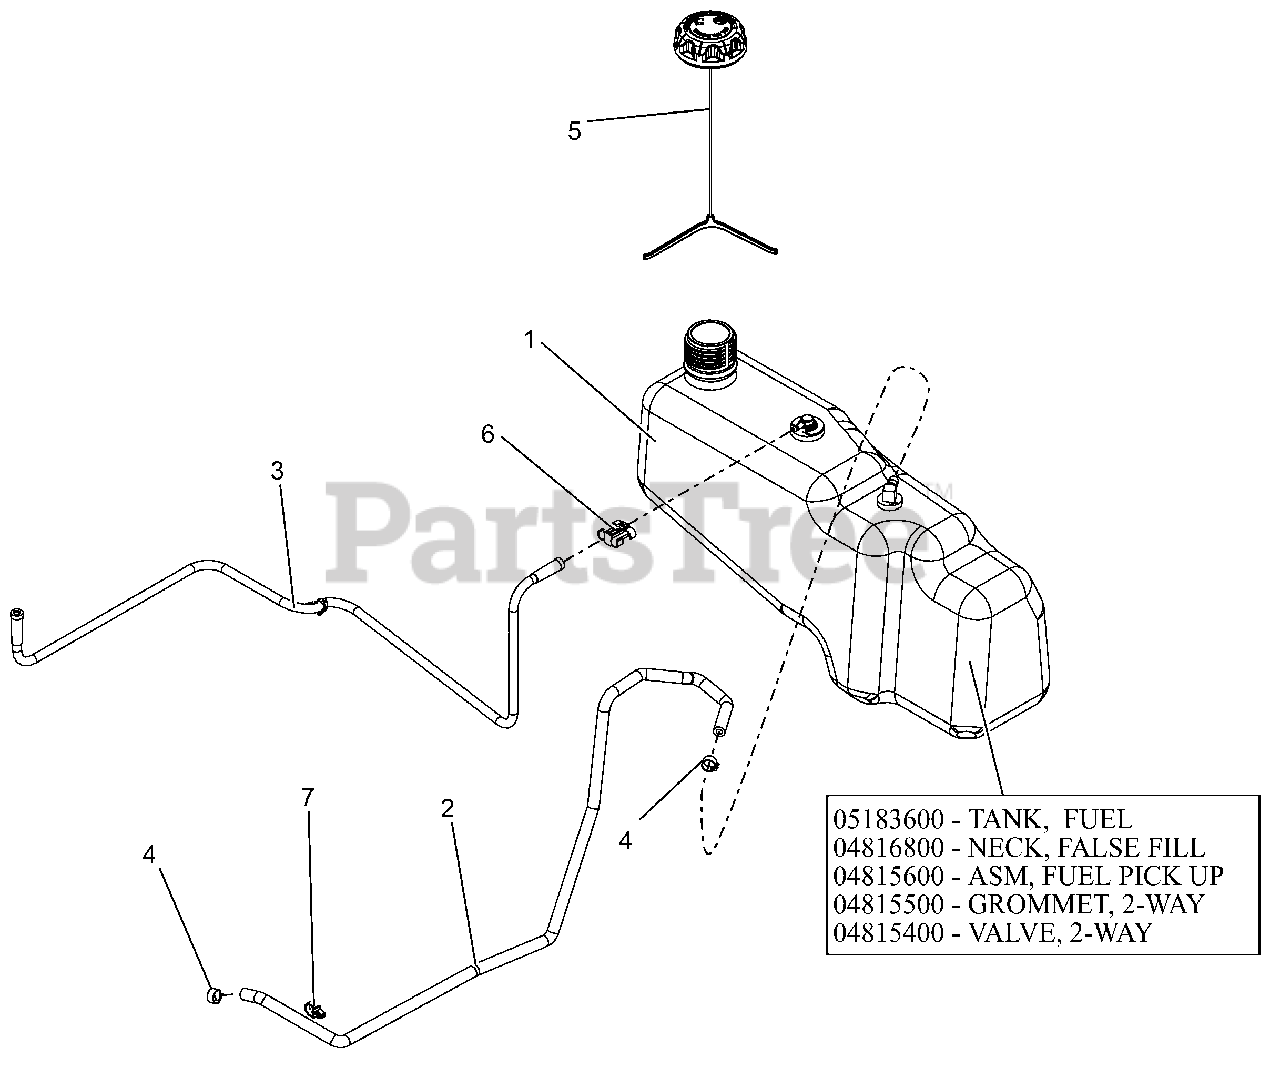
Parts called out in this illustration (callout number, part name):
1	ASM, FUEL TANK - ZTX
1	TANK, FUEL-ZTX
1	NECK, FALSE FILL ZOOM/ZT
1	ASM, FUEL PICK-UP ZOOM/ZT 2015
1	GROMMET, 2-WAY
1	VALVE, 2-WAY
2	HOSE, .25 LOW-PERM BULK GAS
3	LINE, FUEL VENT KOHLER SMCHOKE
4	CLAMP, FUEL LINE
5	CAP, FUEL VENT-IN 2.25" RATCH.
6	CLIP, T, .38-.50
7	ROUTING CLIP (1/2" ID)
